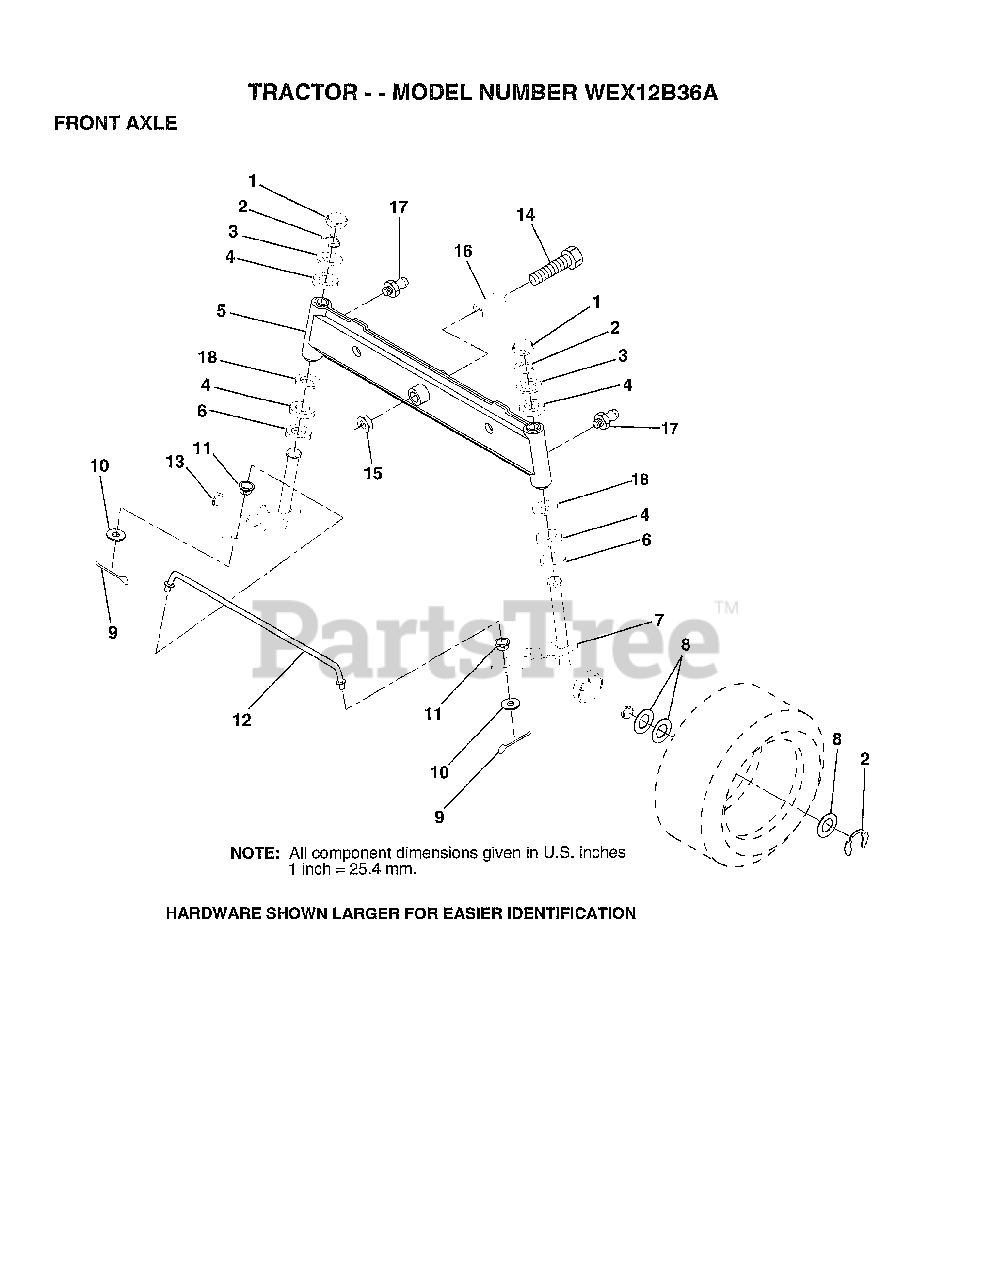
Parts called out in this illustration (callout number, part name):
1	CAP
2	RING
3	WASHER
4	COL. SRTG. BEAR.
5	AXLE ASM FRONT
6	WASHER .T
7	SPINDLE.ASSY.RH
8	WASHER
9	COTTER PIN
10	WASHER
11	BUSHING.DRAGLINK
12	TIE ROD
13	SPINDLE.ASSY.LH
14	BOLT HEX 5/8-11
15	"NUT-LOC,FLANGE LT"
16	BEARING
17	ZERK M
18	WASHER
